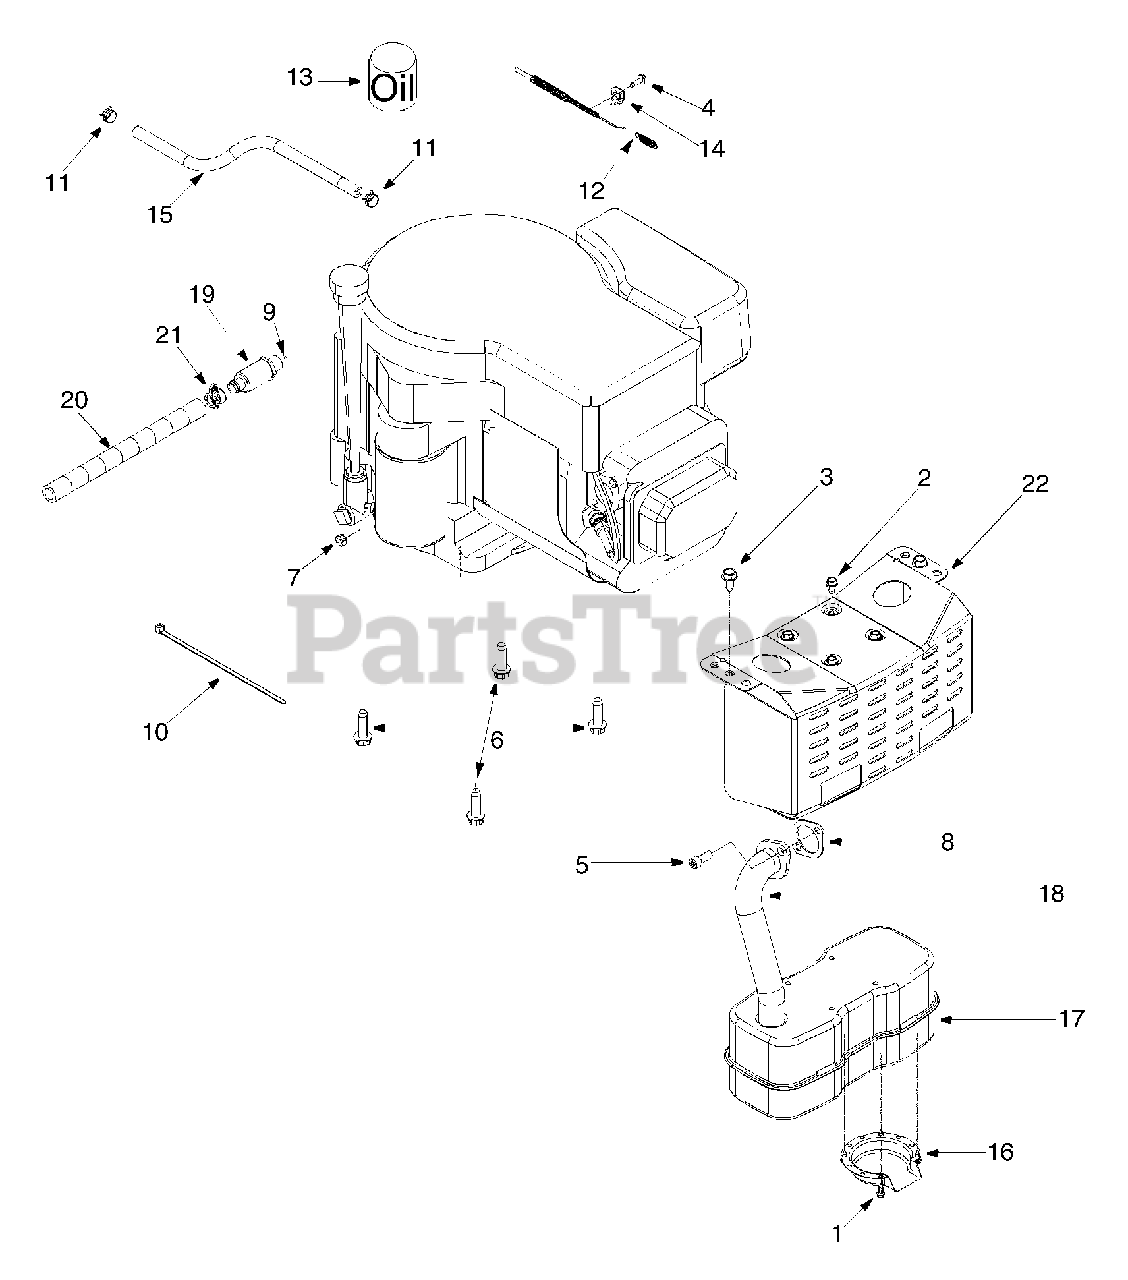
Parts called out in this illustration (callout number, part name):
1	AB Screw #8-18 x 0.5
2	TT Screw 1/4-20 x 0.5
3	AB Screw 5/16-12 x 0.5
4	T screw #10-32 x 0.625
5	Socket Hd Scr. 5/16-18 x.750
6	TT Screw 3/8-16 x 1.25
7	Sems Nut
8	Exhaust Gasket
9	Sealant: Loctite(TM)
10	Cable Tie
11	Hose Clamp
12	Extension Spring
13	SAE 30W Oil
14	Throttle Clamp
15	Fuel Line Hose
16	Muffler Deflector
17	Muffler
18	Exhaust Pipe
19	Oil Drain
20	OIl Drain Extension Hose
21	Oil Drain Cap
